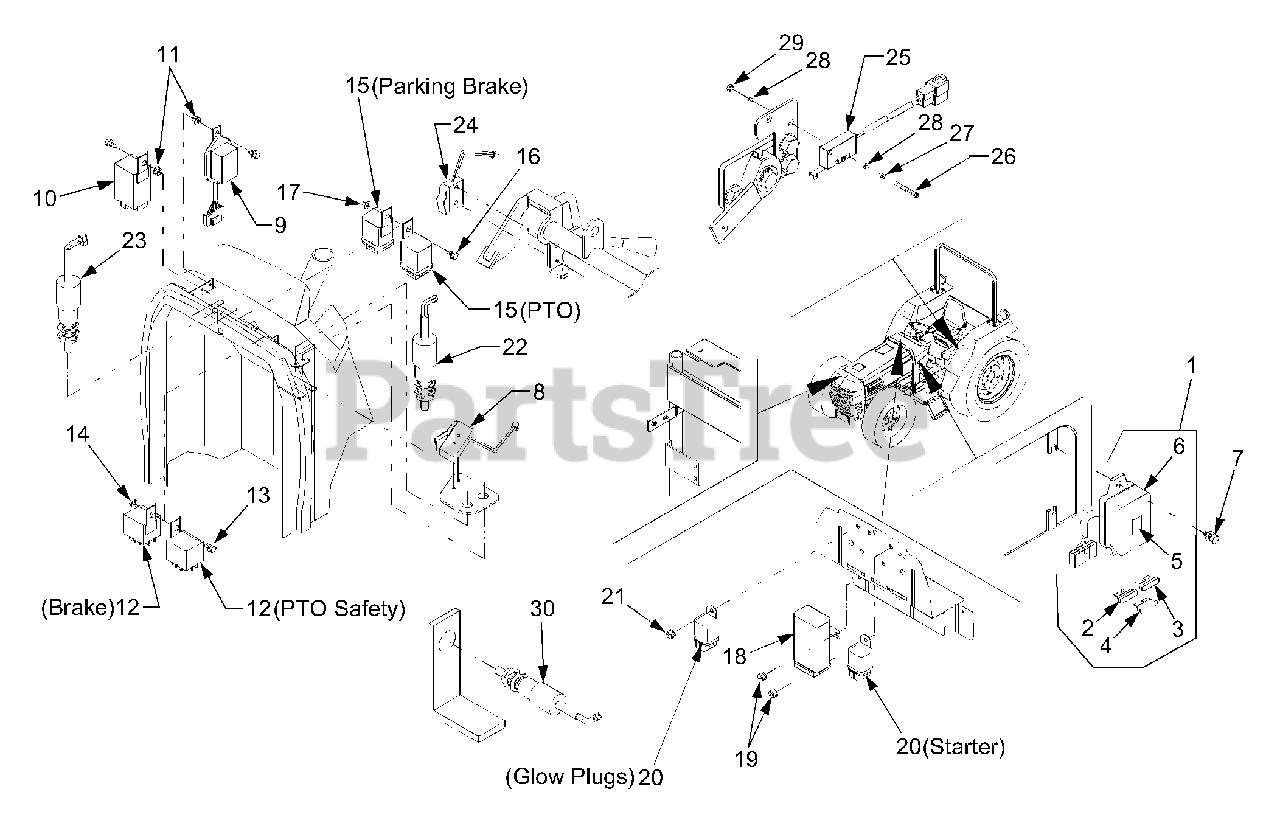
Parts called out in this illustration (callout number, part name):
1	Fuse Box Ass'y
2	Fuse (25a)
3	Fuse (20a)
8	Switch, Micro
9	Relay, Timer
10	Unit, Flasher
18	Controller, Preheater
20	Relay
22	Switch, Safety Starter
23	Stop Switch Ass'y
24	Switch, Micro
25	Switch, Micro
27	Washer, Plain
28	Washer, Spring
30	Safety Starter Ass'y
